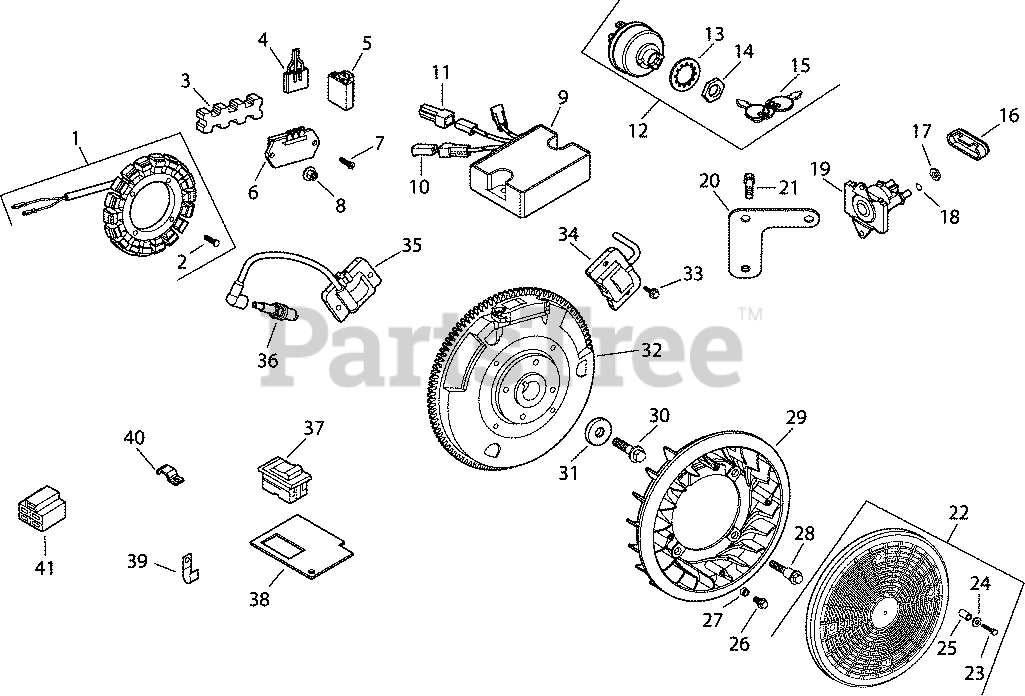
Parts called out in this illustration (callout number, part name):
1	KIT, 15 / 20 AMP STATOR
2	SCREW, M5X0.8X25 - (#25086402S)
4	CONNECTOR, BODY (KM)-USE 25 155 41-S
6	REG/RECT-15 AMP (KM)-USE 41 403 10-S
7	SCREW, FLG THD FRM M5X.8X20-(#25086399S)
22	KIT, GRASS SCREEN
23	SCREW, SLT HD CAP M4X0.7X25
24	WASHER, FLAT 3/16"
25	SPACER - DISCONTINUED
28	BOLT, SHOULDER
29	FAN - (#DSC)
30	SCREW, FLG M10X1.5X45 - (#25086361S)
31	WASHER, FLAT 13/32"
32	FLYWHEEL - (#DSC)
33	SCREW, FLG THD FRM M5X.8X20-(#25086399S)
34	MODULE, IGNITION - #1 CYLINDER-USE 24 58
35	MODULE, #2 CYLINDER-USE 66 584 09-S
36	PLUG, SPARK (STD)
